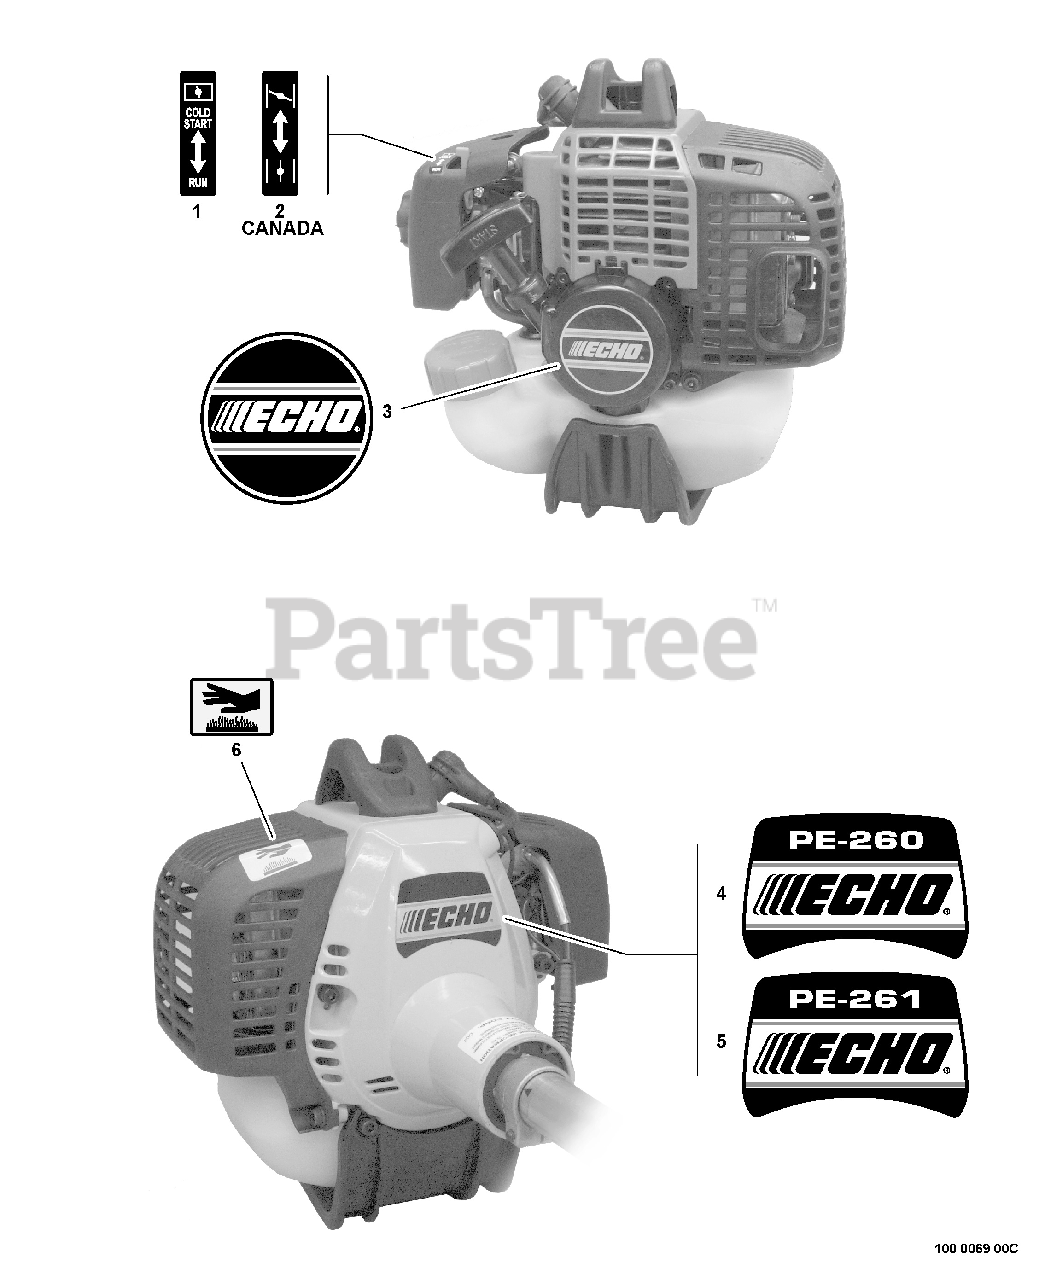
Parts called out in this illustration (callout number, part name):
1	LABEL - CHOKE
2	LABEL - CHOKE
3	LABEL - ECHO
4	LABEL - SPARK PLUG -- BPM-8Y
5	LABEL - SPARK PLUG -- BPMR-8Y
6	LABEL - MODEL PE-260
7	LABEL - MODEL PE-261
8	LABEL - HOT SURFACE
